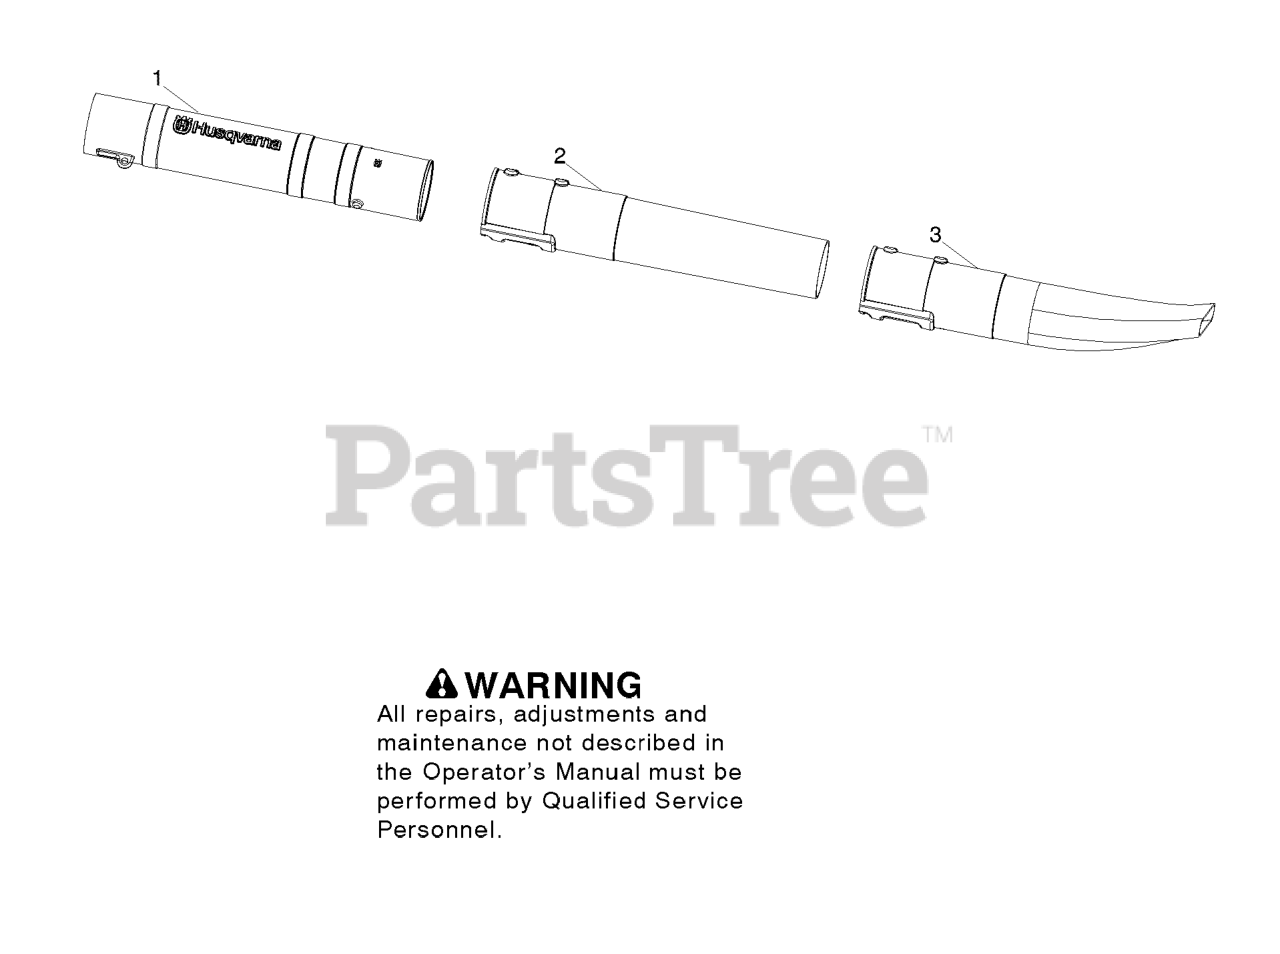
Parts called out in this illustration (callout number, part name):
1	ASSY TUBE BLOWER W/BARR
2	TUBE, LOWER
3	FLARE, LOWER TUBE
